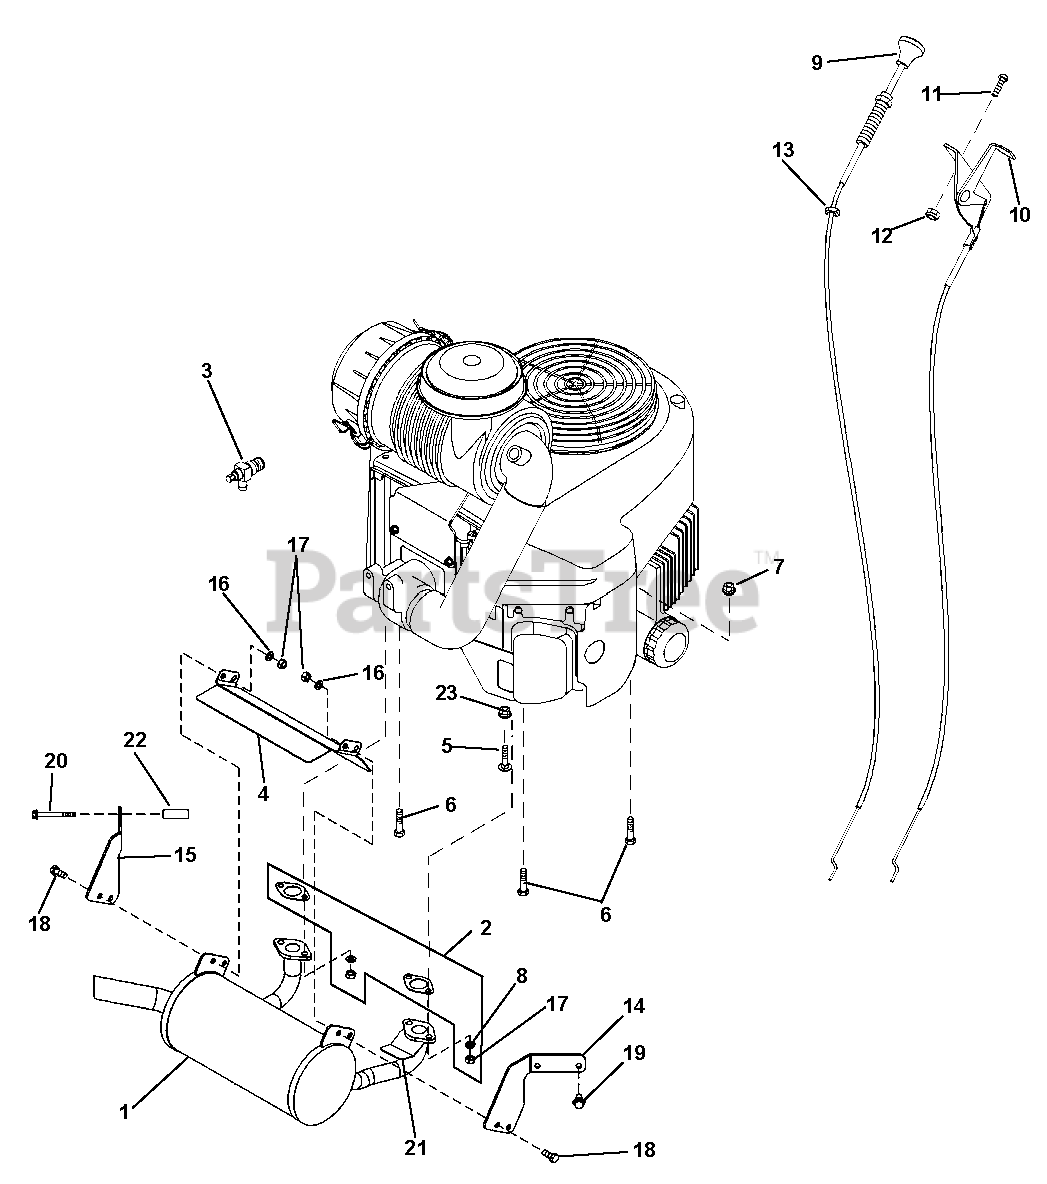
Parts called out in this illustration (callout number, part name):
1	Muffler (994103)
2	Gasket Kit, (Includes Gaskets, items 8 and 17)
3	Oil Drain Fitting
4	Muffler Shield (994103)
5	Carriage Bolt, Engine Mounting M8 x1.25 x 50
6	Cap Screw, Engine Mounting M8 x 1.2
7	Nut, Locking, Nylon M8-1.25
8	Washer, Lock .31 x .078
9	Cable, Choke
10	Cable, Throttle
11	Bolt, Hex, 8-32 x .5
12	Nut, Locking, Nylon 8-32 With Insert
13	Nut, Hex .38-24
14	Bracket, Muffler Support RH (994103)
15	Bracket, Muffler Support LH (994103)
16	Washer, Helical Spring
17	Nut, Hex, M8-1.25
18	Bolt, Hex, M8-1.250 x 20
19	Bolt, Hex, M8 x 1.25 x 16
20	Screw, Flanged Metric M6 x 60
21	Shield, Heat (994103)
22	Spacer, Reverse Pedal Assembly
23	Bolt, Hex, M8 x 1.25 x 16
24	Air Filter 19 (994100)
25	Oil Filter (994100)
26	Fuel Filter-Kawasaki (994100)
27	Spark Plug, 19 HP Kawasaki (994100)
